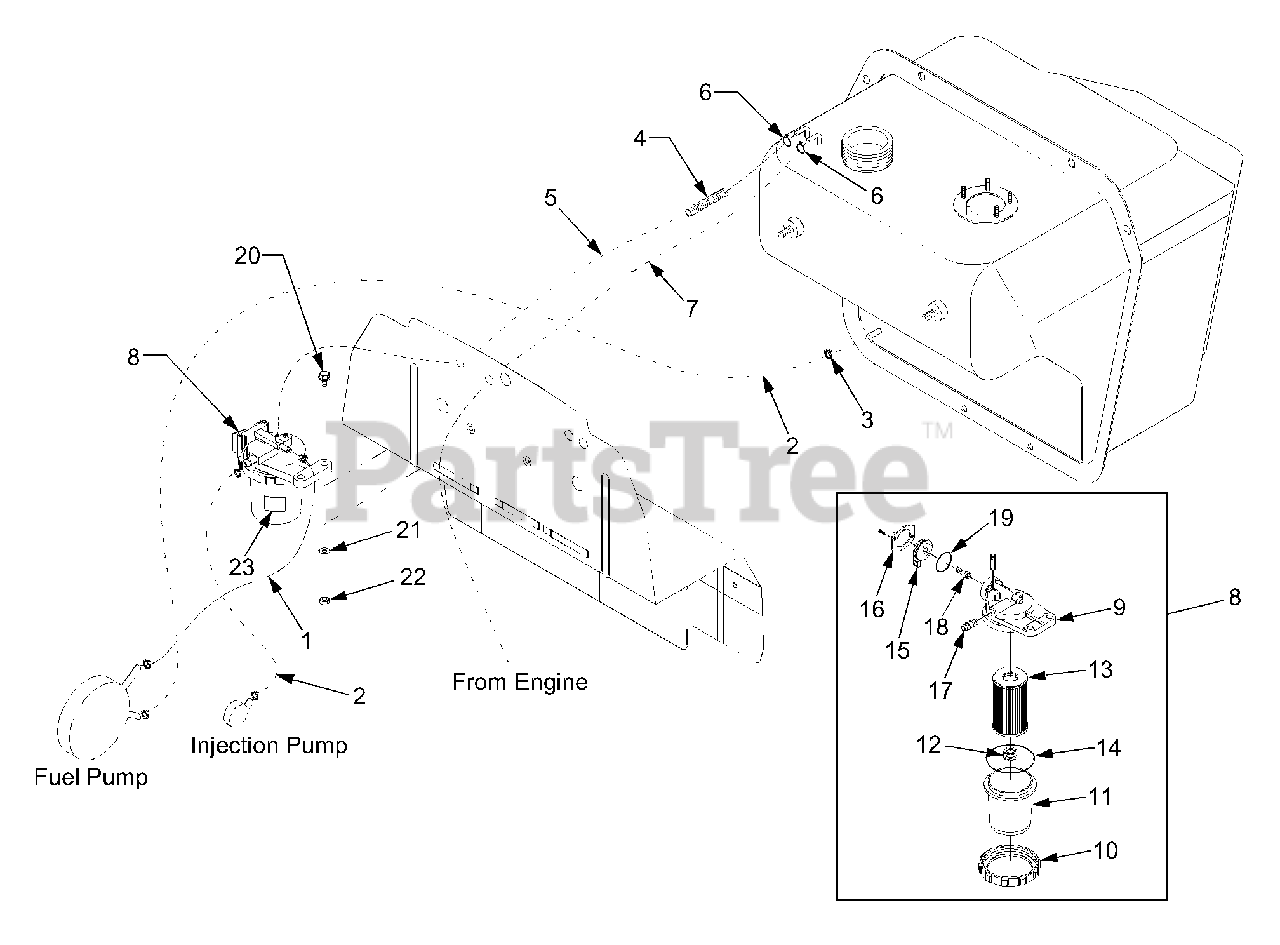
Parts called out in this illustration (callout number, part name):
8	Fuel Filter Ass'y
9	Body, Fuel Filter
11	Pot, Filter
13	Element, Filter
16	Support, Handle
21	Washer, Spring
23	Label (Fuel Filter)
